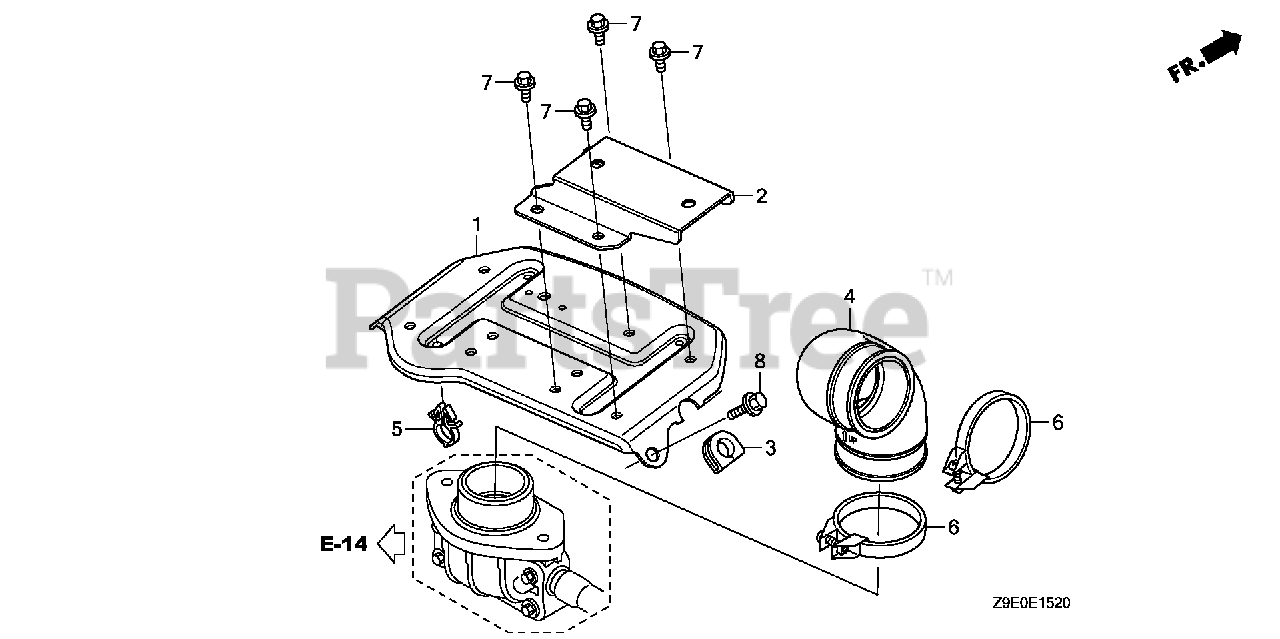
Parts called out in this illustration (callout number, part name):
1	STAY, AIR CLEANER
2	SUB-STAY, AIR CLEANER
3	GROMMET, AIR CLEANER STAY
4	TUBE, AIR CLEANER CONNECTING
5	CLIP, WIRE HARNESS
6	BAND, AIR CLEANER CONNECTING TUBE (58)
7	BOLT, FLANGE (6X12)
8	BOLT, FLANGE (8X16)
